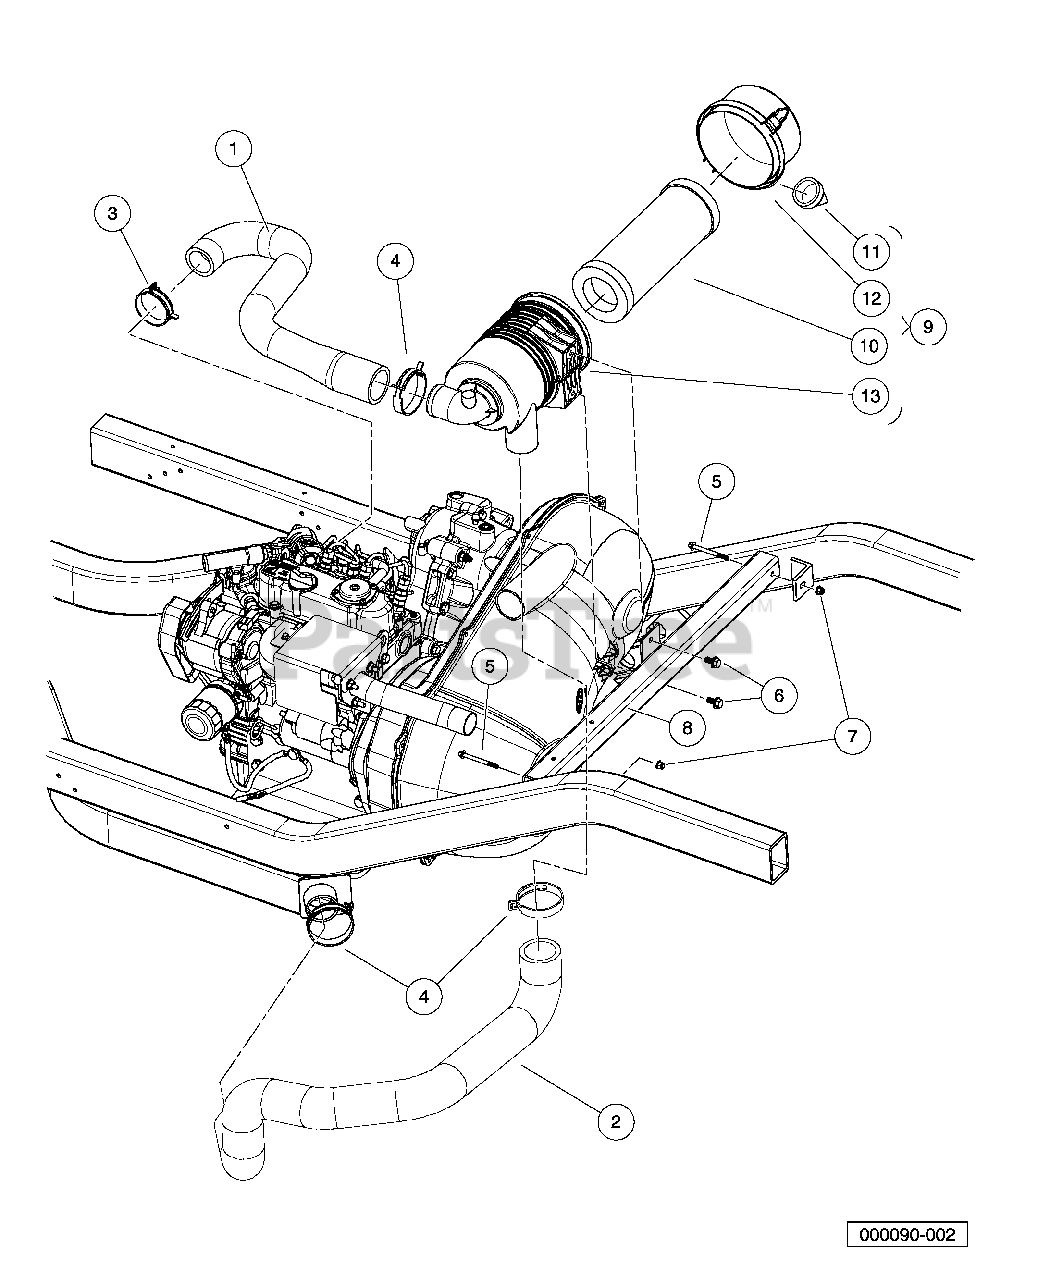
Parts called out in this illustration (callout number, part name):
1	Hose, Intake, D722
2	Hose, Intake, Primary
3	Clamp, Hose, Ctb 55mm
4	Clamp, Hose, Ctb 64mm
5	Bolt, M 6 X 1.0 X 65 Hex, Flange, Head, Black
6	Bolt Flanged Head, M8 X1.25x 16 with Loctite
7	Nut Flg, M6 X 1.0 Nylon
8	Weldment, Support, Air Cleaner
9	Filter, Air, Canister, W/labe
10	Element, Filter, Air, 5 In
11	Valve, Evacuator, Filter Air
12	Cap, Latch Lock, Filter, Air
13	Body, Canister, Filter, Air
